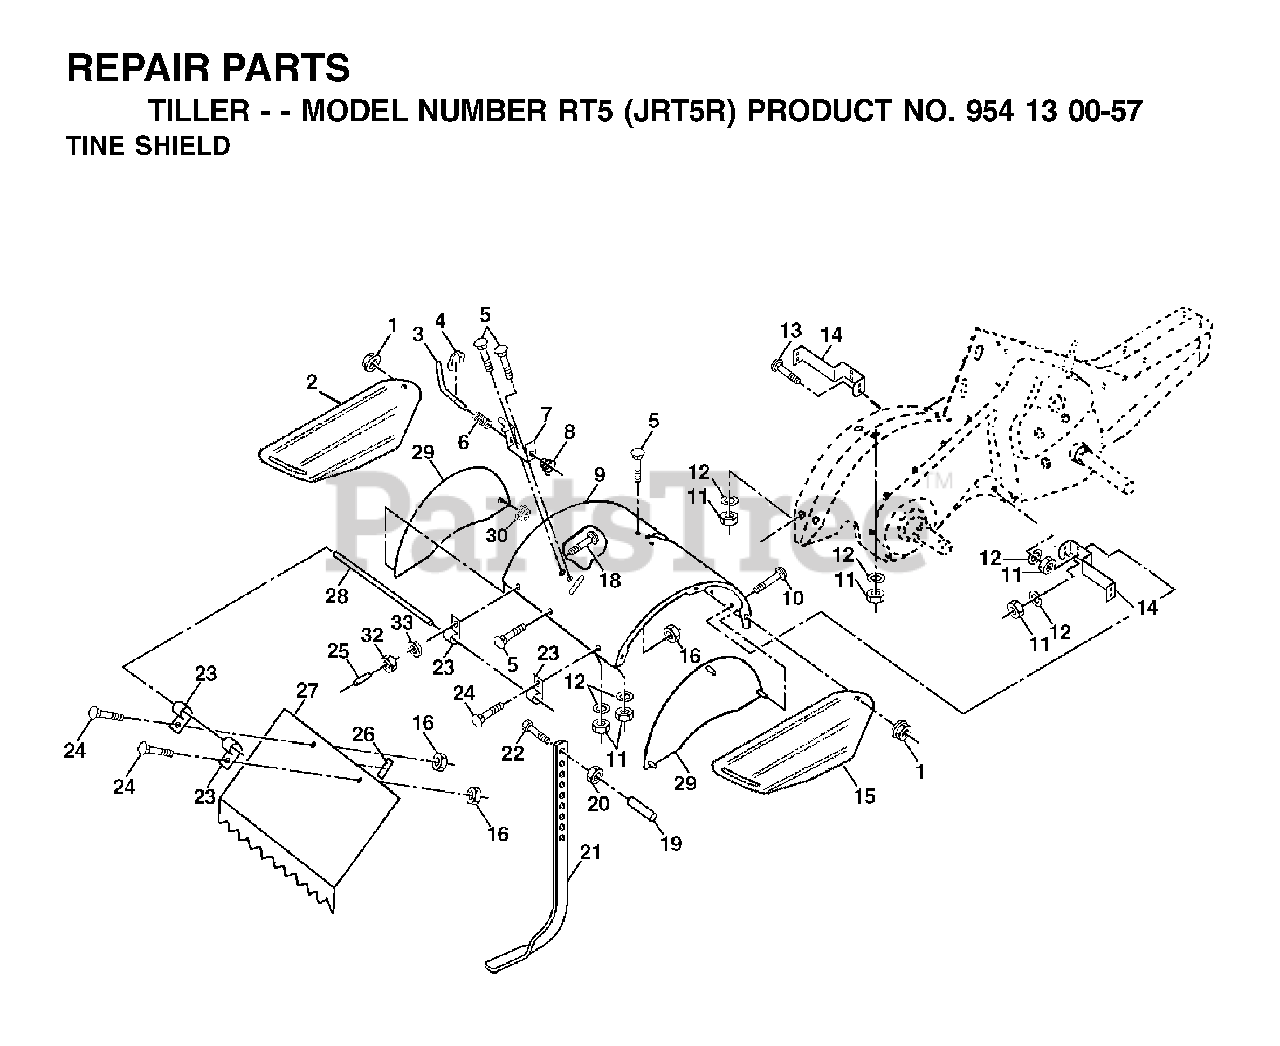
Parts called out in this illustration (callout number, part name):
1	NUT LOCK HEX FLANGE 5/16-18
3	STAKE PIN TI
4	RING, KLIP
5	BOLT
6	SPRING TI
7	LATCH BRACKET TI
8	SPRING CRT
10	BOLT
12	LOCKWASHER
13	BOLT.CARRIAGE.5/16-18
14	BRACKET.TINE.SHIELD.TILLER
16	NUT T
20	NUT.HEX.3/8-16UNC
21	STAKE DEPTH CRT
22	BOLT.375-16
23	HINGE CRT
25	VINYL CAP TI
26	PAD IDLER TI
28	PIN.HINGE.TILLER
30	LOCKNUT-FLANGE 5/16-18
32	NUT
33	LOCKWASHER
